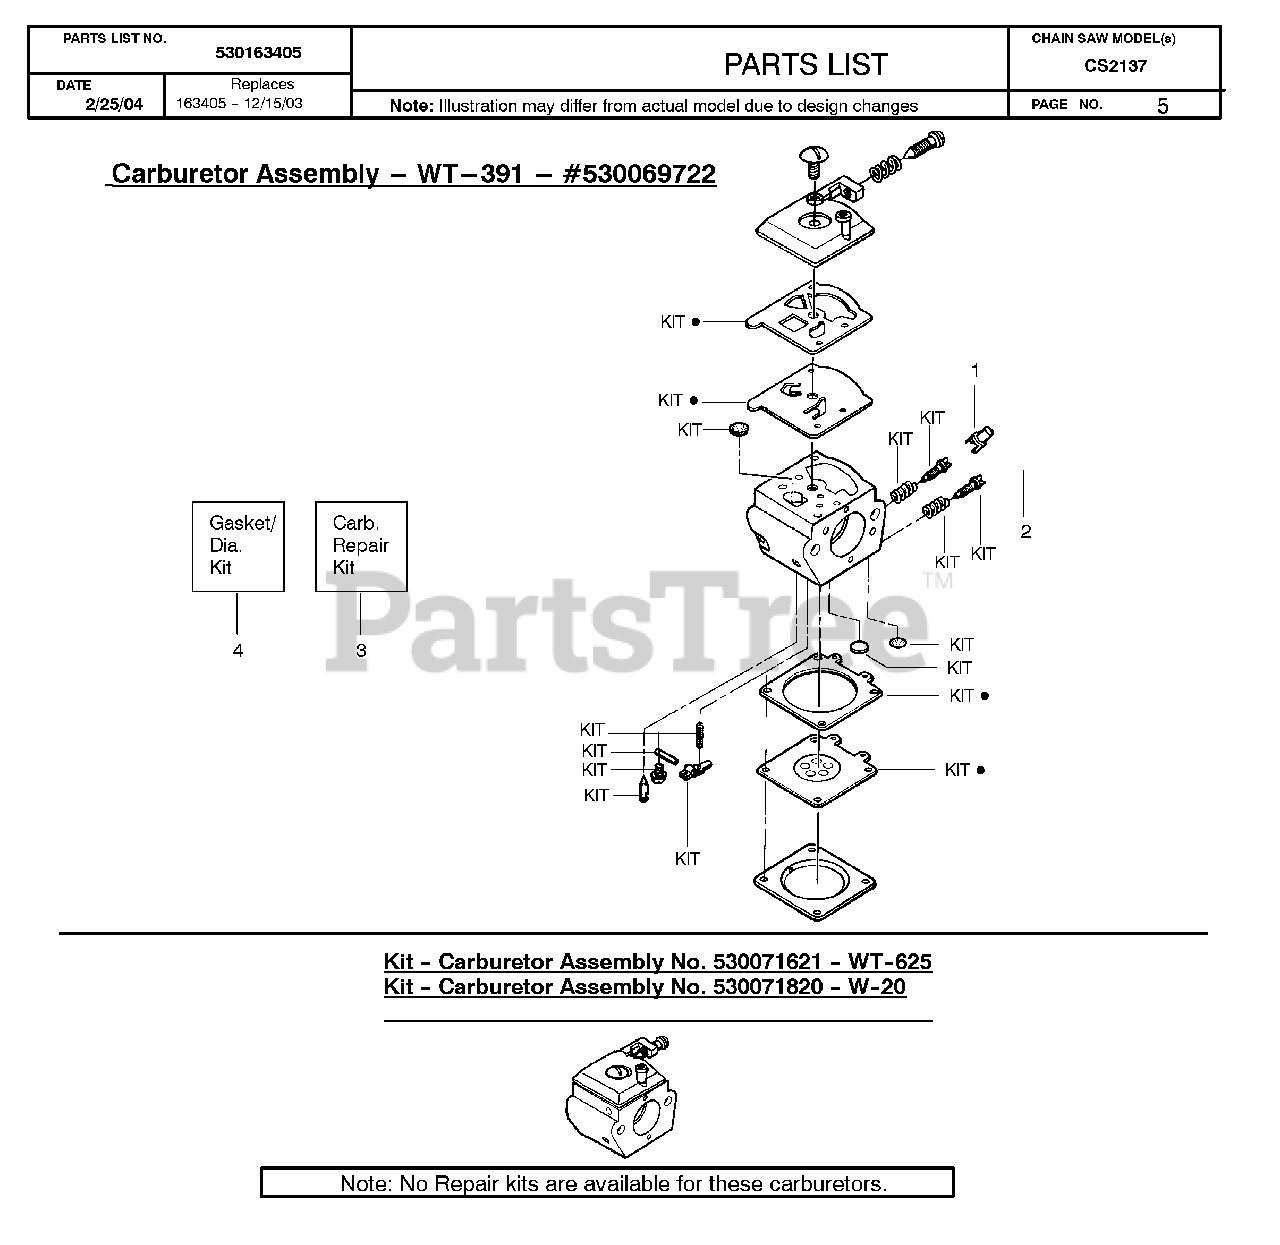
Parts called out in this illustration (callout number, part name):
1	LIMITER CAP-HIGH
2	LIMITER CAP-LOW
3	CARB REPAIR KIT
4	GASKET/DIAPHRAGM KIT
